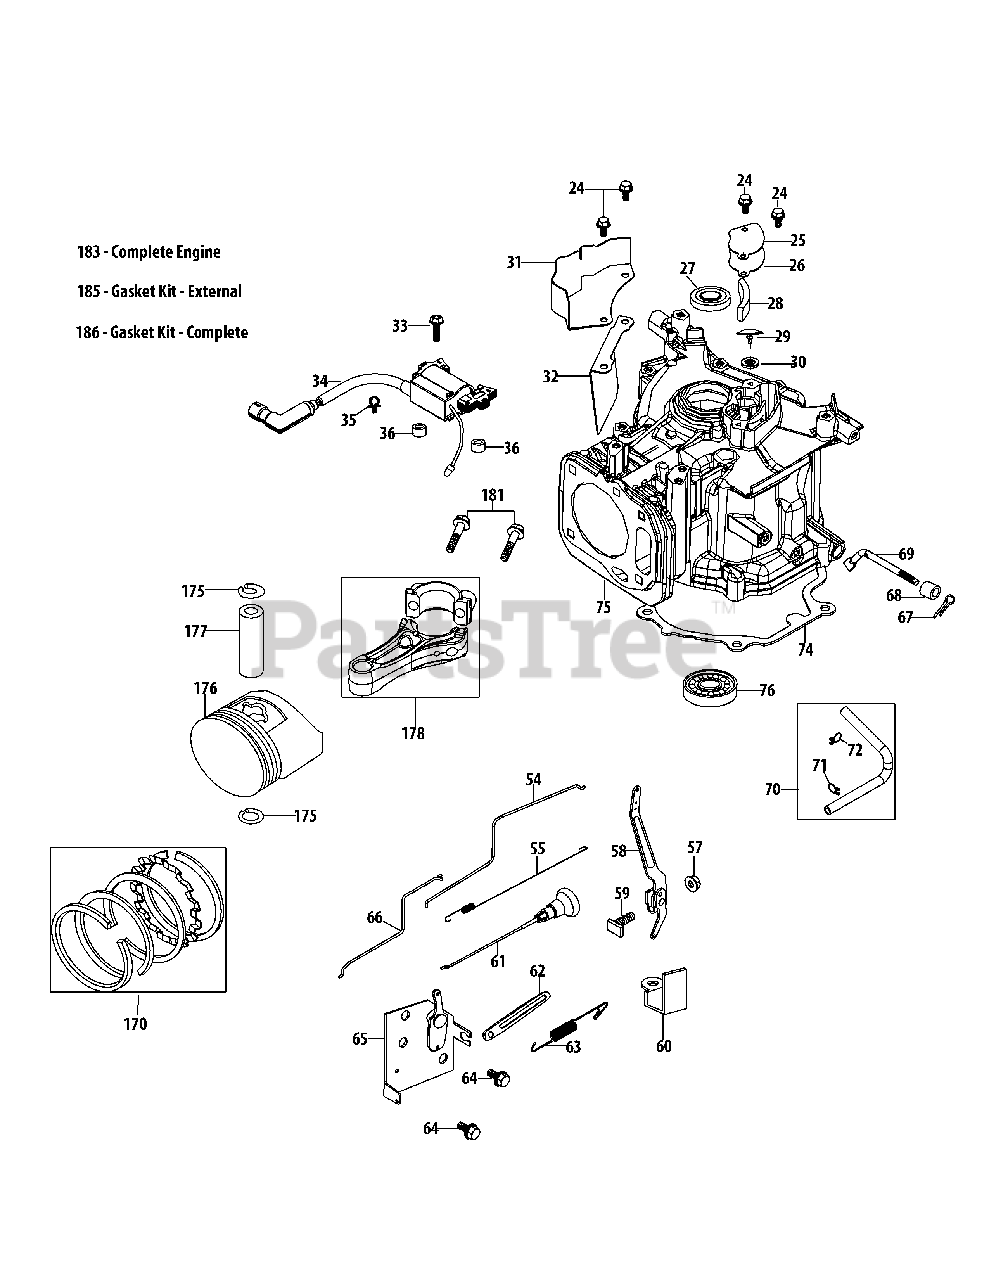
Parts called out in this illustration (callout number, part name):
24	Bolt M6X14 Multi-Purpose
25	Breather Cover Plate
26	Breather Gasket
27	Upper Crankshaft Seal
28	Breather Screen
29	Breather Valve
30	Breather Valve Base
31	Engine Brake Cover Plate
32	Label Bracket
33	Bolt M6X30
34	Ignition Coil Assembly
35	Ignition Wire Clip
36	Ignition Coil Spacer
54	Throttle Linkage
55	Throttle Linkage Spring
57	Governor Arm Nut M6
58	Governor Arm
59	Governor Arm Bolt
60	Governor Arm Guard
61	Choke Control
62	Flexible Clamp
63	Governor Spring
64	Bolt M6X12
65	Component Bracket
66	Choke Linkage
67	Governor Arm Shaft Cotter Pin
68	Governor Seal
69	Governor Arm Shaft
70	Breather Hose Assembly
71	Breather Hose Clamp
72	Breather Hose Clamp
74	Crankcase Cover Gasket
75	Short Block
76	Main Bearing
170	Piston Ring Set
175	Piston Pin Snap Ring
176	Piston
177	Piston Pin
178	Connecting Rod Assembly
181	Connecting Rod Bolt
183	Complete Engine
185	Gasket Kit - External
186	Gasket Kit - Complete
